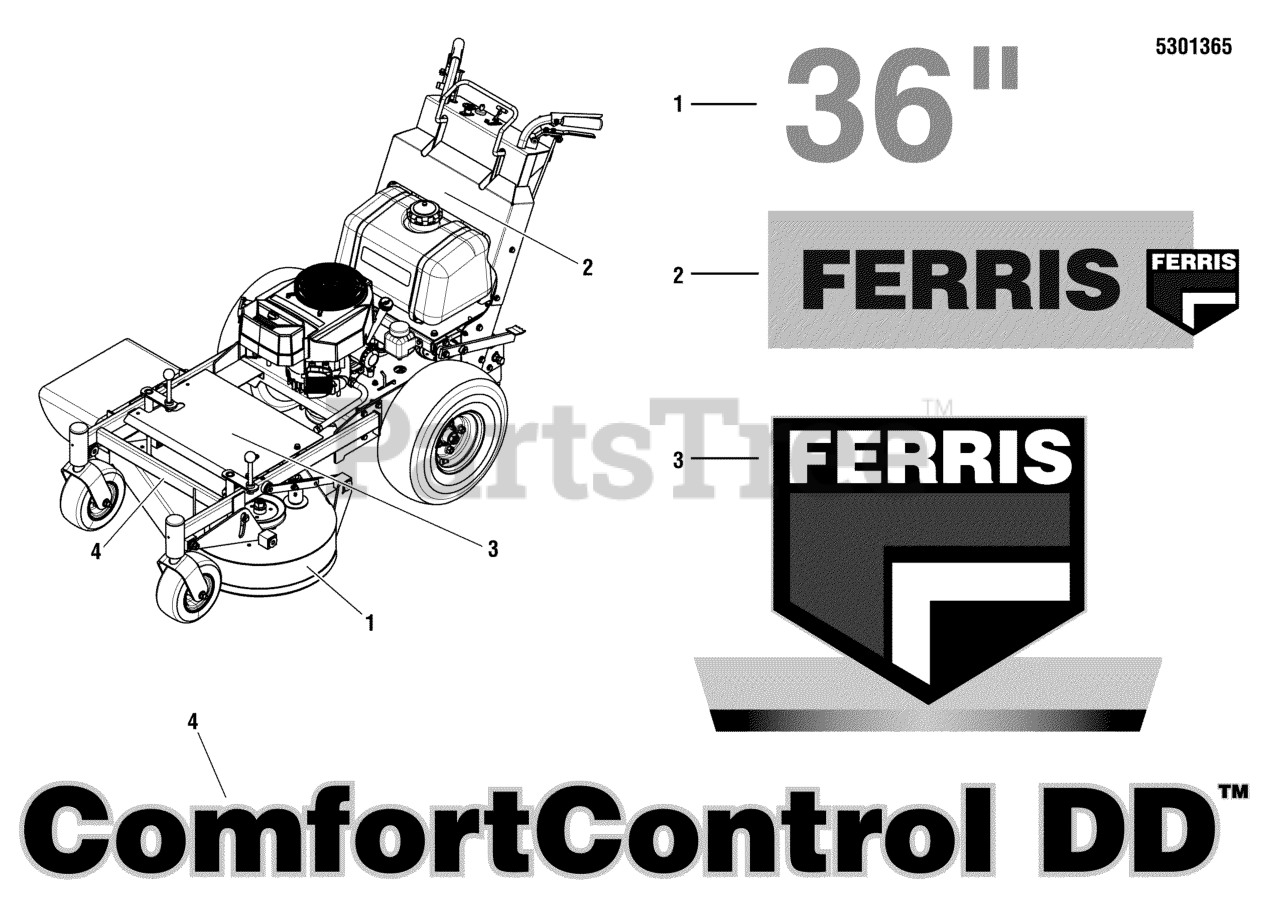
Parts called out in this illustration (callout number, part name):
1	DECAL, 36"
2	DECAL, FERRIS TEXT & LOGO
3	DECAL, FERRIS SHIELD
4	DECAL, COMFORT CONTROL
